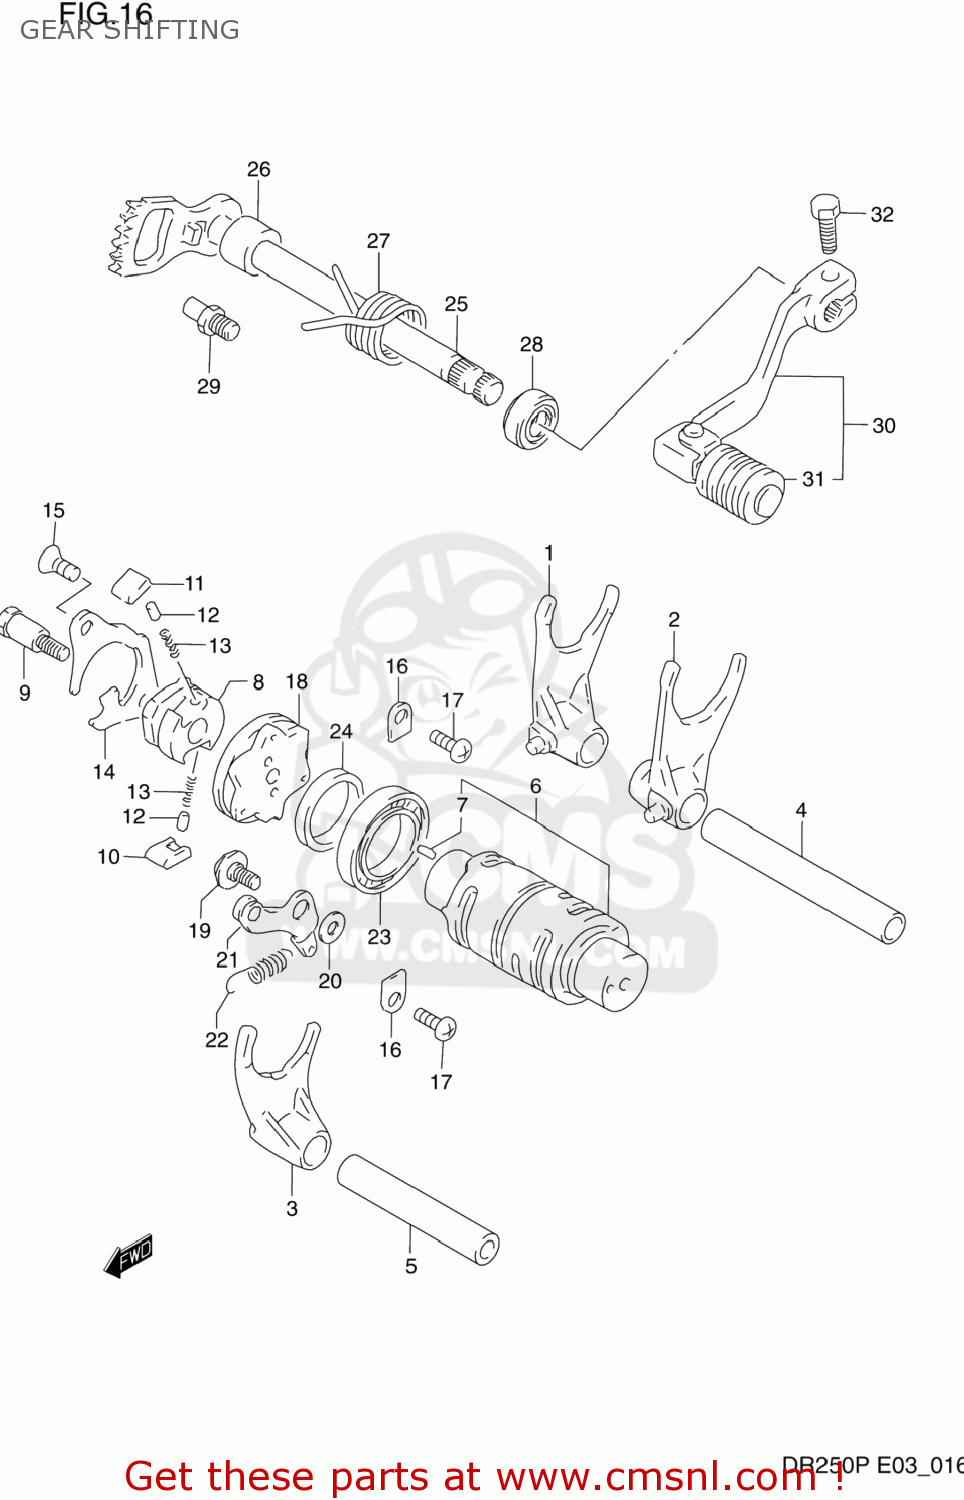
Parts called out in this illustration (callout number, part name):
1	FORK,GEAR SHIFT NO.1
2	FORK,GEAR SHIFT NO.2
3	FORK,GEAR SHIFT NO.3
4	SHAFT,GEAR SHIFT FORK
5	SHAFT,GEAR SHIFT FORK(L:70)
6	CAM,GEAR SHIFT
7	PIN
8	GEAR,GEARSHIFT CAM DRIVE
9	PIN,SHIFT CAM DRIVEN GEAR
10	PAWL,GEAR SHIFT NO.1
11	PAWL,GEAR SHIFT NO.2
12	PIN(5X8)
13	SPRING
14	LIFTER,GEAR SHIFT PAWL
15	SCREW
16	RETAINER
17	SCREW 6X12
18	PLATE,GEAR SHIFT CAM
19	BOLT(6X14.3)
20	WASHER
21	STOPPER,GEAR SHIFT CAM
22	SPRING
23	BEARING
24	WASHER(25X32X5.3)
25	SHAFT,GEAR SHIFT
26	SPACER(12X20X15.3)
27	SPRING
28	OIL SEAL
29	STOPPER,GEAR SHIFT ARM
30	LEVER ASSY,GEAR SHIFT
31	RUBBER,GEAR SHIFT PEDAL
32	BOLT
